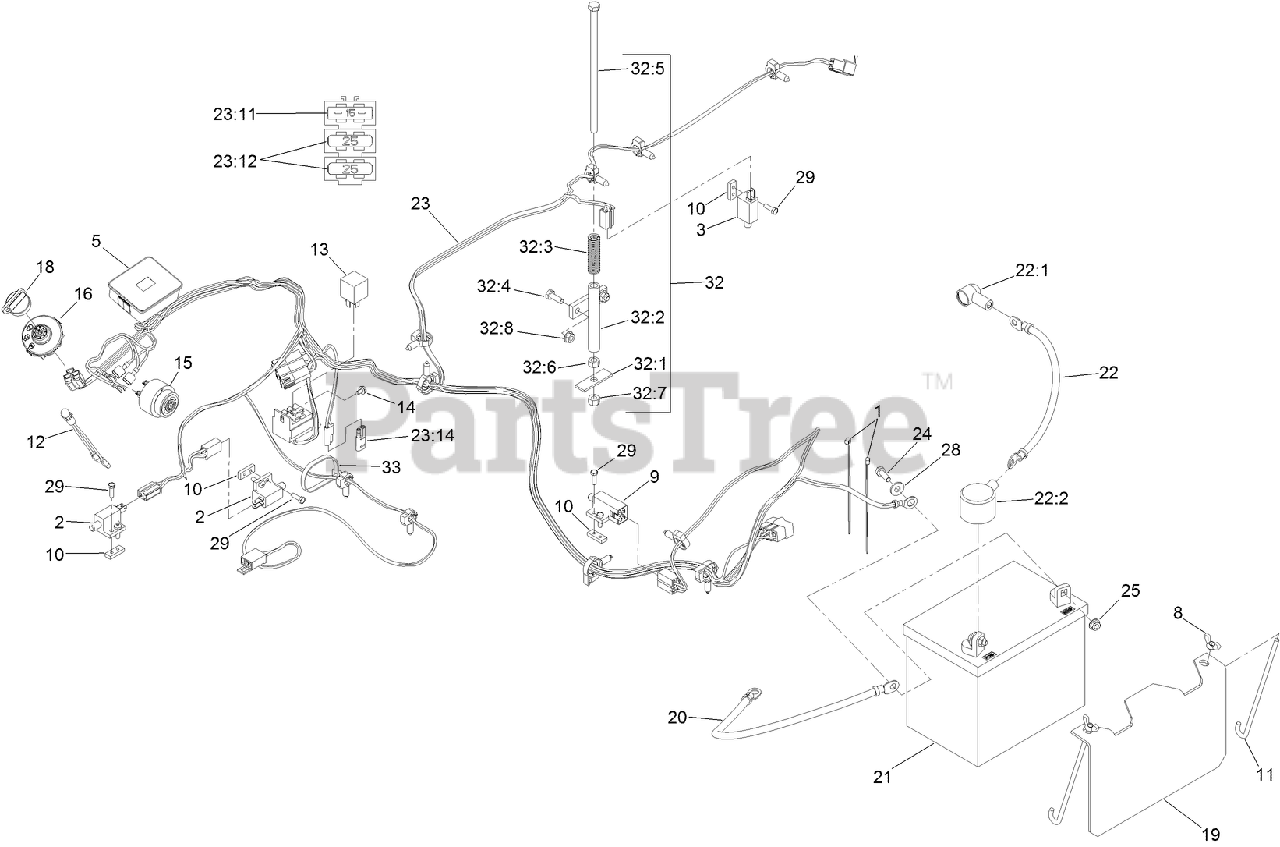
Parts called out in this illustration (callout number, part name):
1	TIE-CABLE
2	SWITCH-OPEN, NORMALLY
3	SWITCH-CLOSED, NORMALLY
5	HOUR METER ASM
8	WINGNUT
9	SWITCH
10	PLATE-TAPPED
11	BOLT-HOLDDOWN
12	INDICATOR-LED, RED
14	SCREW-HWH
15	ALARM-TONE, DUAL
16	SWITCH-IGNITION
18	KEY-IGNITION
19	HOLD DOWN-BATTERY
20	CABLE-BATTERY, NEGATIVE
21	BATTERY (300 CCA, WET)
22	CABLE-BATTERY, POSITIVE
22:1	INSULATOR-SOLENOID
22:2	INSULATOR-BATTERY
23	HARNESS-WIRING
23:11	FUSE-BLADE, 15 AMP
23:12	FUSE-BLADE, 25 AMP
23:14	CAP-PLUG
24	SCREW-HH
25	NUT-HF
28	WASHER-FLAT
32	HOPPER SWITCH ACTUATOR ASM
32:1	PLATE-SWITCH, SEAT
32:2	MOUNT-SPRING, SEAT
32:3	SPRING-SWITCH, SEAT
32:4	SCREW-HH
32:5	SCREW-HH
32:6	NUT-HEX
32:7	NUT-LOCK, NI
32:8	NUT-HF
33	TIE-PLASTIC
